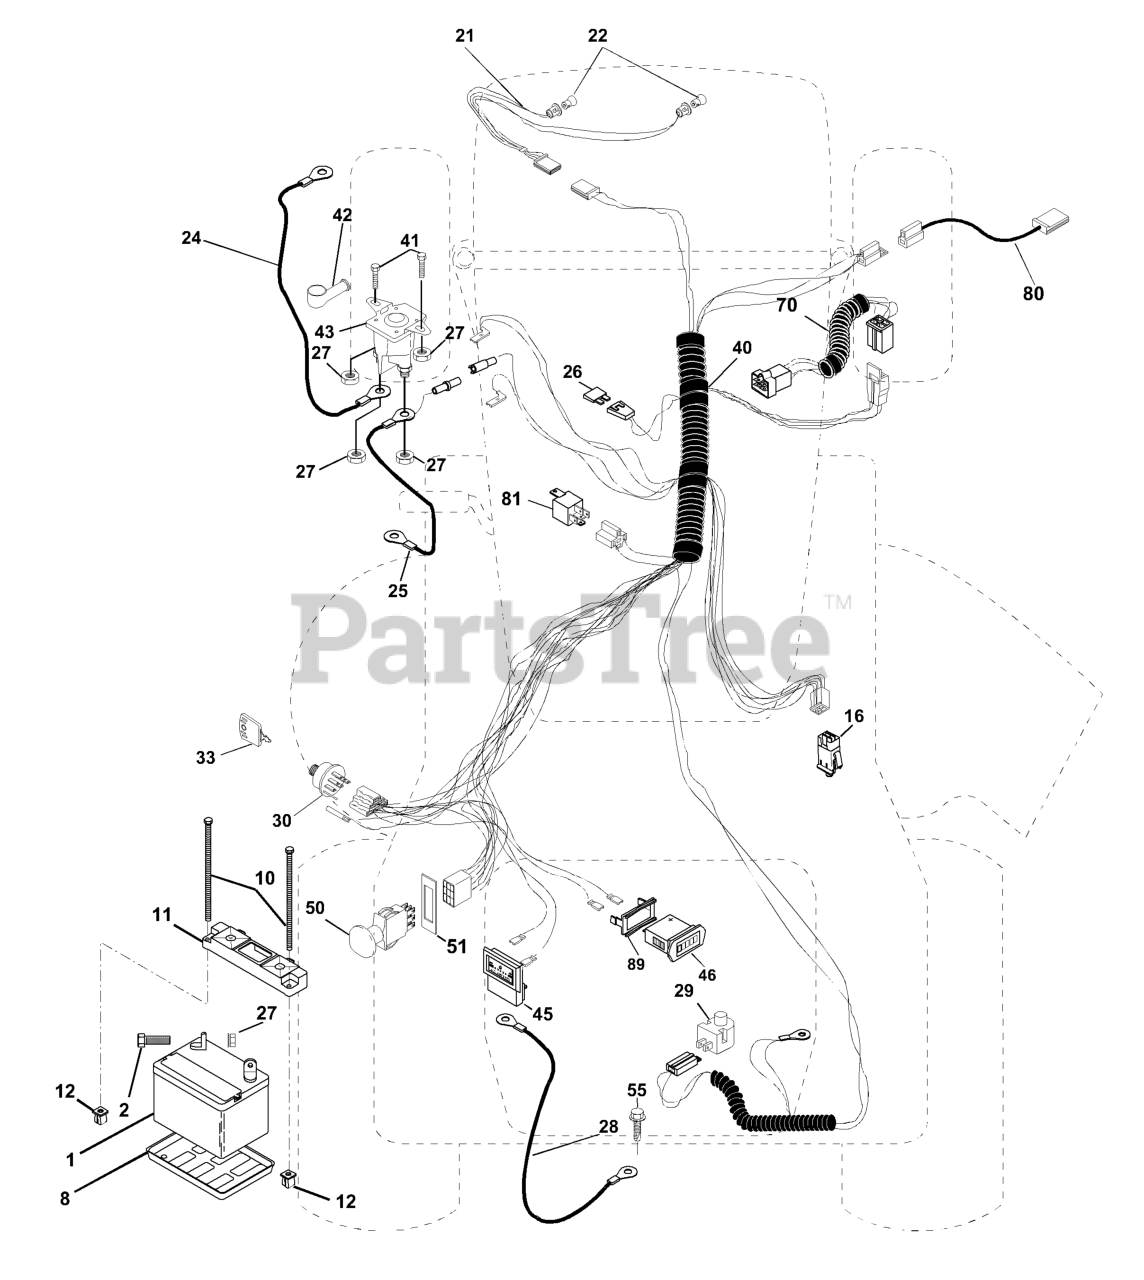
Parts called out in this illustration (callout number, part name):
1	BATTERY 12V .35 AMP
2	BOLT
8	BATTERY TRAY T
10	BOLT, BTR FRT 1/4-20X4-1/2ZINC
11	BATTERY HOLDDOWN FRONT MOUNT
12	NUT, PUSH NYLON 1/4" BATTERY
16	SWITCH INTERLOCK
24	BATTERY CABLE GT
25	CABLE BATTERY 6 GA 22" W/16W
26	FUSE 15 AMP
27	NUT
28	CABLE GROUND 6 GA 21" 90T BLK
29	PLUNGER SWITCH (COLOR:OLIVE)
30	SWITCH IGN
33	KEY MLD GEN DELTA
40	HARNESS IGN.
41	BOLT
42	TERMINAL COVER
43	SOLINOID
46	HOUR METER
50	PTO SWITCH
51	FRAME RETAINING RING
55	Screw, Thdrol 5/16-18 x 1/2 TYT
70	Harness, Engine
80	HARNESS, CLUTCH
81	RELAY.ASSY.T
89	BRACKET SNAP-IN HOURMETER
